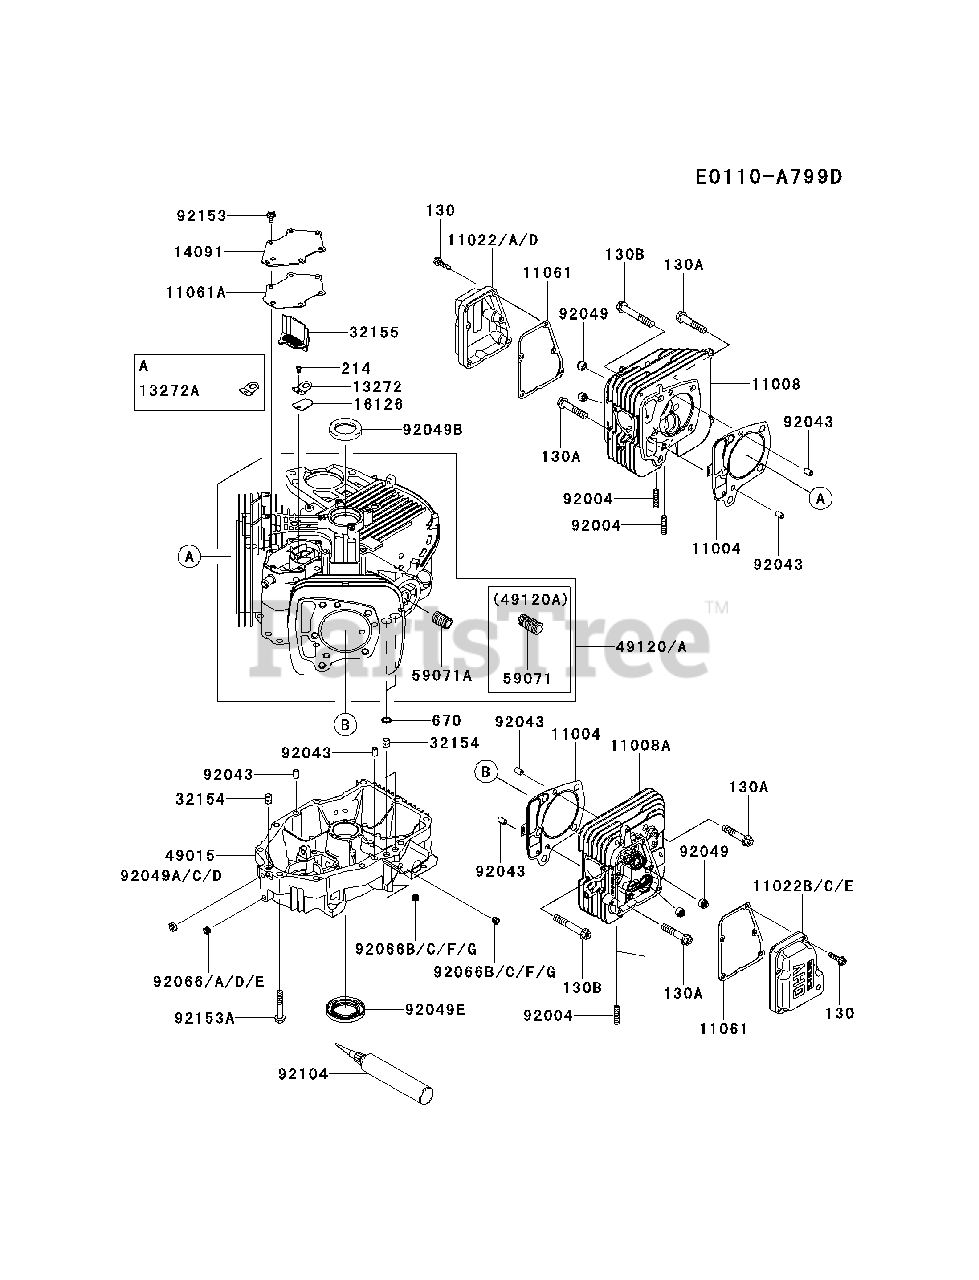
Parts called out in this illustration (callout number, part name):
130	BOLT-FLANGED,6X25
130A	BOLT-FLANGED,10X50
130B	BOLT-FLANGED,10X65
214	SCREW-PAN+-,4X8
670	O RING,11MM
